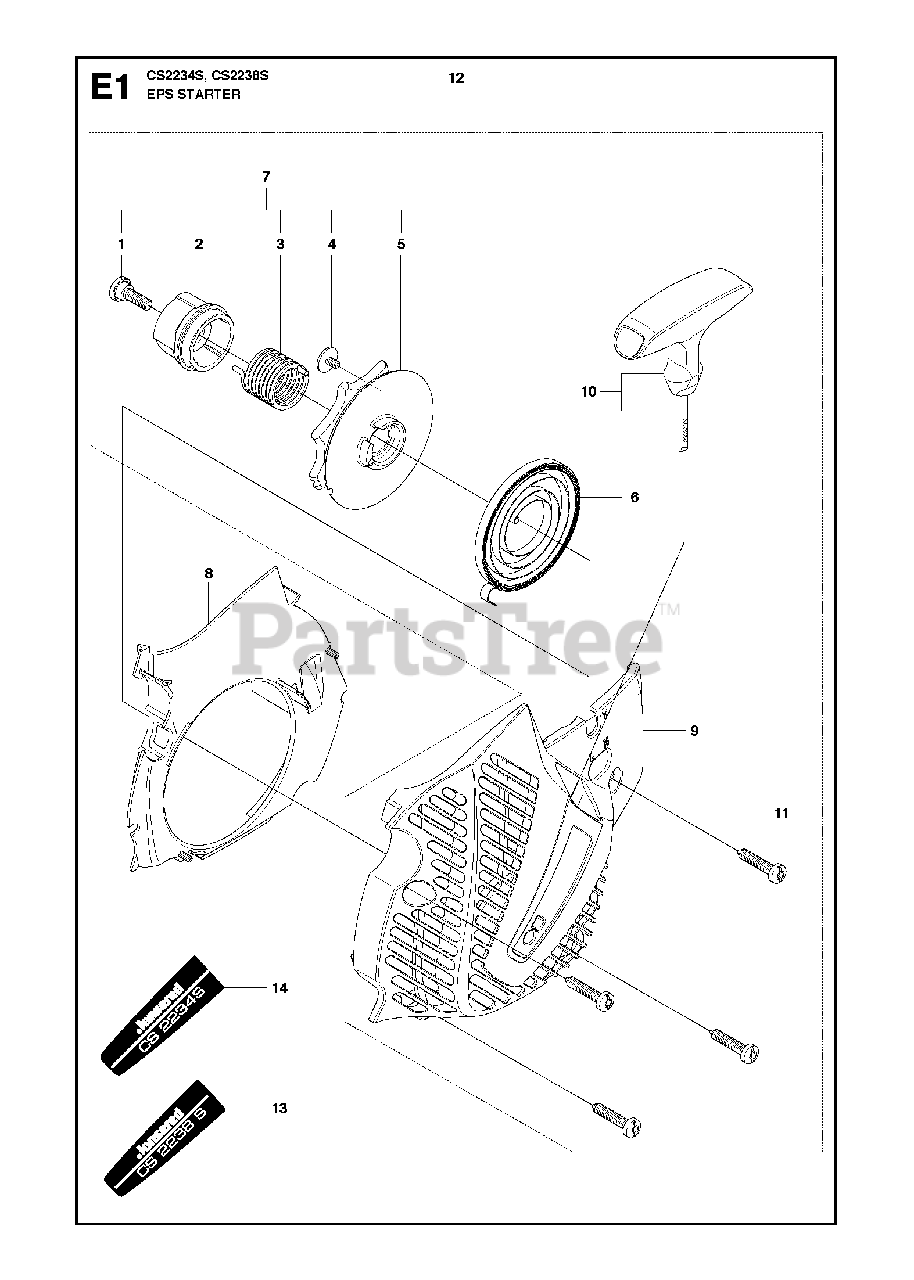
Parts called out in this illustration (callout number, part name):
1	SCREW SHOULDER
2	HUB STARTER EPS
3	SPRING EPS
4	SCREW
5	PULLEY STARTER EPS
6	SPRING STARTER
7	KIT EPS STARTER
11	SCREW M5.38-14X22.225MM
